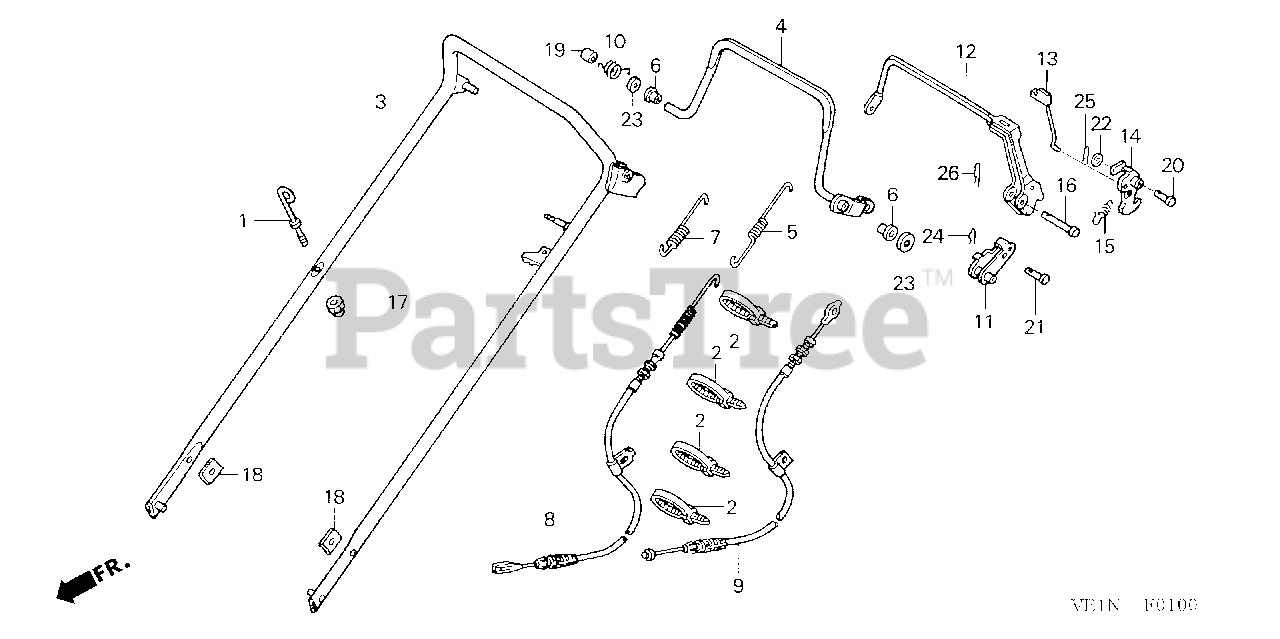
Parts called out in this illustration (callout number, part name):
1	GUIDE, ROPE
2	TIE, CABLE (157.5MM)
3	PIPE, HANDLE *NH105* (MAT BLACK)
4	LEVER, CLUTCH
5	SPRING, CLUTCH
6	BUSH, CLUTCH LEVER
7	SPRING, CLUTCH LEVER RETURN
9	CABLE, ROTO-STOP
10	SPRING, R. STOP RETURN
11	ARM, ROTO-STOP CABLE
12	LEVER, ROTO-STOP
12	LEVER, ROTO-STOP (FOR U.S.A.)
13	ROD, RATCHET PUSH
14	LEVER, LOCK
15	SPRING, RATCHET RETURN
16	PIN, CLUTCH LEVER
17	NUT, NYLON LOCK (6MM)
18	WASHER, FRAME JOINT
19	COLLAR (8X11X13.5)
20	PIN, LOCK LEVER HINGE (6X30)
21	PIN, CABLE JOINT
22	WASHER, PLAIN (6MM)
23	WASHER, PLAIN (8MM)
24	PIN, SPLIT (1.6X12)
25	PIN, LOCK (6MM)
26	PIN, LOCK (8MM)
